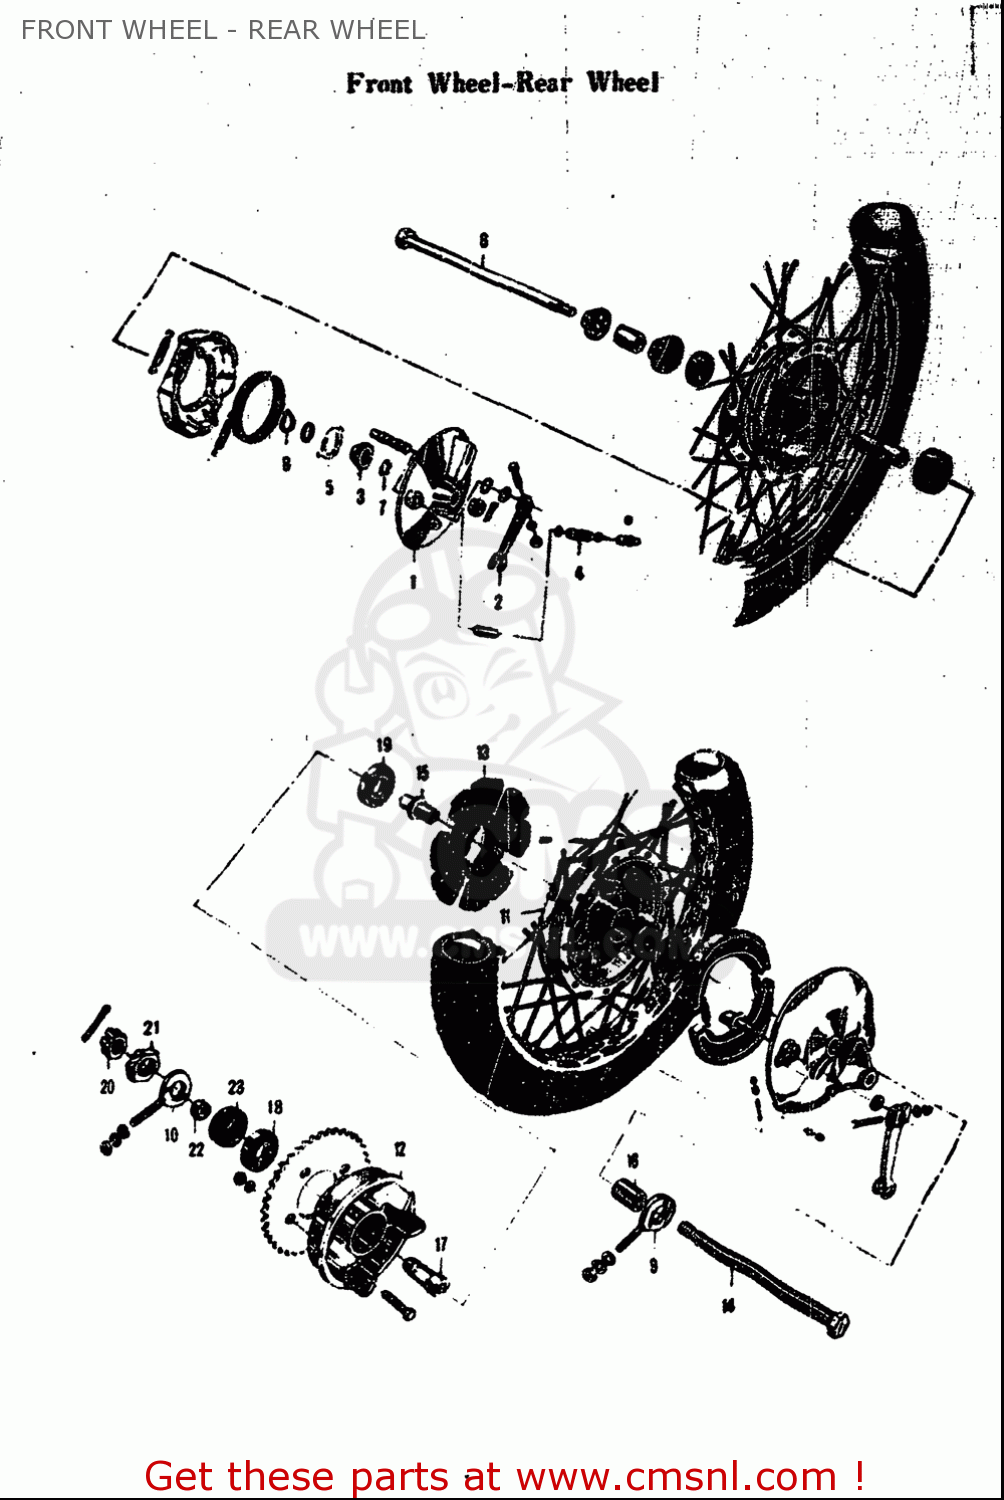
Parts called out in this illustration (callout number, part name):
2	LEVER,FR BRAKE CAM
3	GEAR,SPEEDOMETER(NT:24)
7	WASHER(16X22X1)
8	CIRCLIP
9	ADJUSTER,CHAIN,R
13	ABSORBER,RR WHEEL HUB SHOCK
17	SHAFT,RR SPROCKET DRUM
18	BEARING(17X40X12)
19	BEARING
20	NUT
21	NUT
22	SPACER(17X25X10.5)
